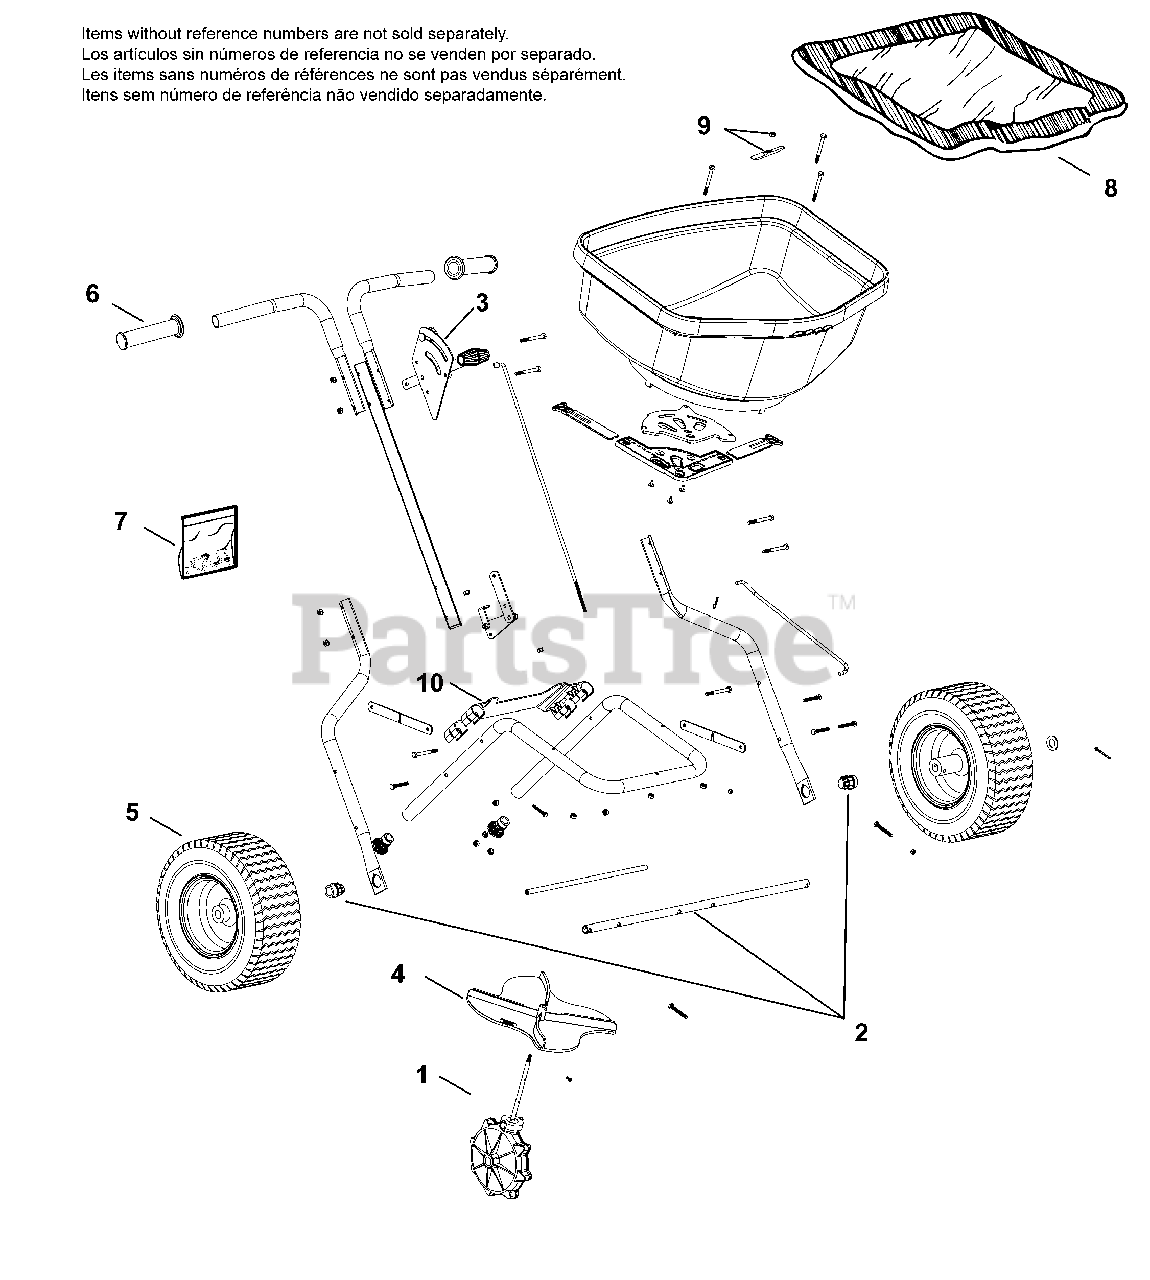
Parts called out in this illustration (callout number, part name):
1	GEAR BOX ASSEMBLY
2	DRIVE SHAFT W/2 BUSHINGS
3	GATE CONTROL ASSEMBLY, ZINC
4	IMPELLER & SECURING SCREW ASSEMBLY
5	RB-80 TIRE & RIM ASSEMBLY 12”
6	HANDLE GRIPS
7	HARDWARE BAG, ZINC
8	RAIN COVER
9	AUGER & LOCK NUT ASSEMBLY
10	REAR BAFFLE
